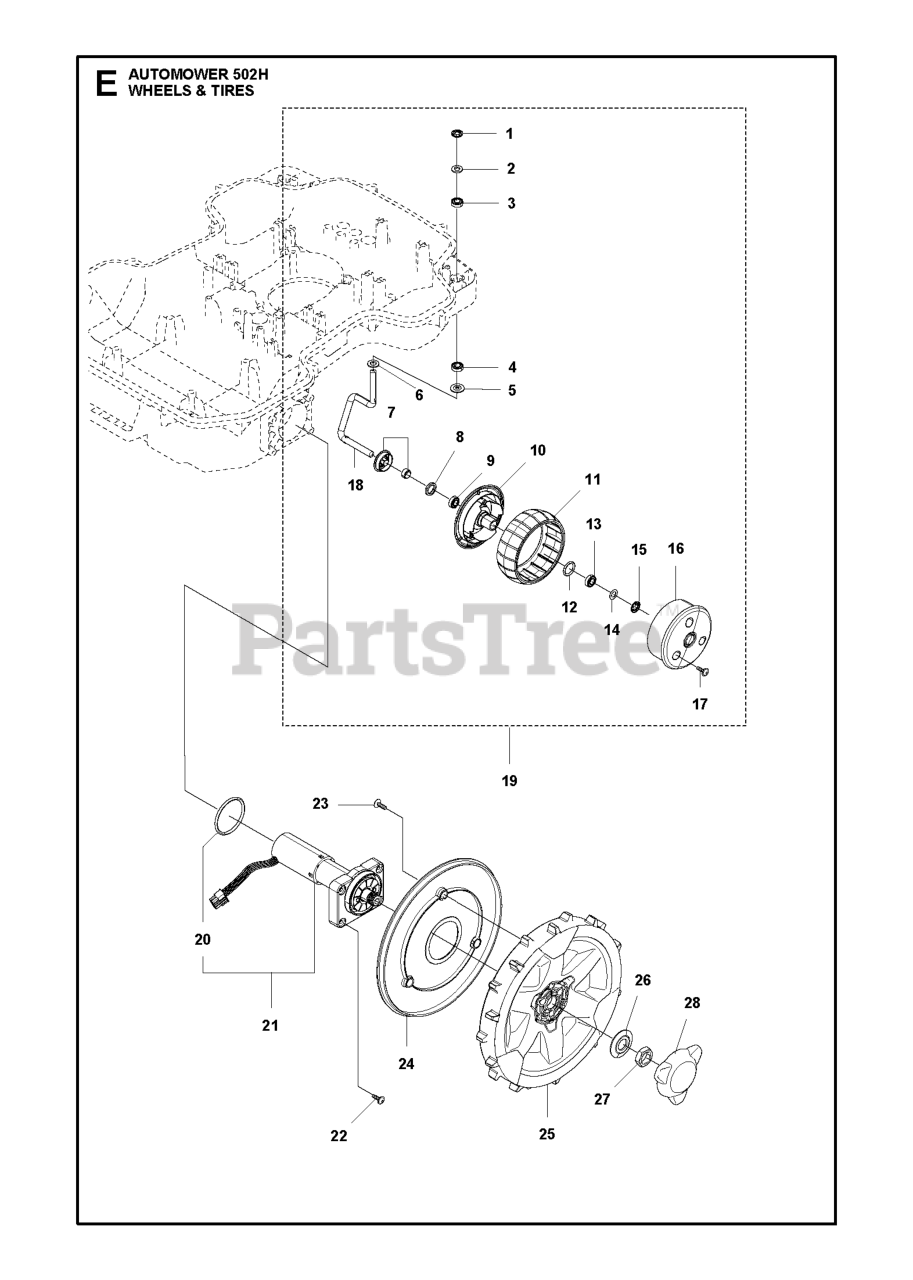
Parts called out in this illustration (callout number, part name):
1	LOCKWASHER PUSH-ON TYPE P 8 BV
2	WASHER DIN 988 13X8X0.5
3	BALL BEARING SINGLE ROW S688
4	BALL BEARING SINGLE ROW S688
5	WASHER FRONT WHEEL CENTER HOLE
6	WASHER DIN 988 13X8X0.5
7	SHIELD KIT
8	SEALING 12X18X3
9	BALL BEARING SINGLE ROW S688
10	WHEEL FRONT WHEEL INSIDE
11	WHEEL RUBBER TYRE
12	O-RING 2,62X15,54
13	BALL BEARING SINGLE ROW S688
14	WASHER DIN 988 13X8X0.5
15	LOCKWASHER PUSH-ON TYPE P 8 BV
16	WHEEL FRONT WHEEL OUTSIDE
17	SCREW 14MM
18	SPINDLE SPINDLE FRONT WHEEL RI
19	WHEEL KIT FRONT
20	O-RING LIGHT GREY
21	Motor
22	SCREW ITXPANT
23	SCREW 14MM
24	COVER REAR WHEEL
25	REAR WHEEL COARSE THREAD LIGHT
26	WASHER WASHER REAR WHEEL 16X40
27	HEXAGON THIN NUT
28	HUB CAP REAR WHEEL NO CENTER P
